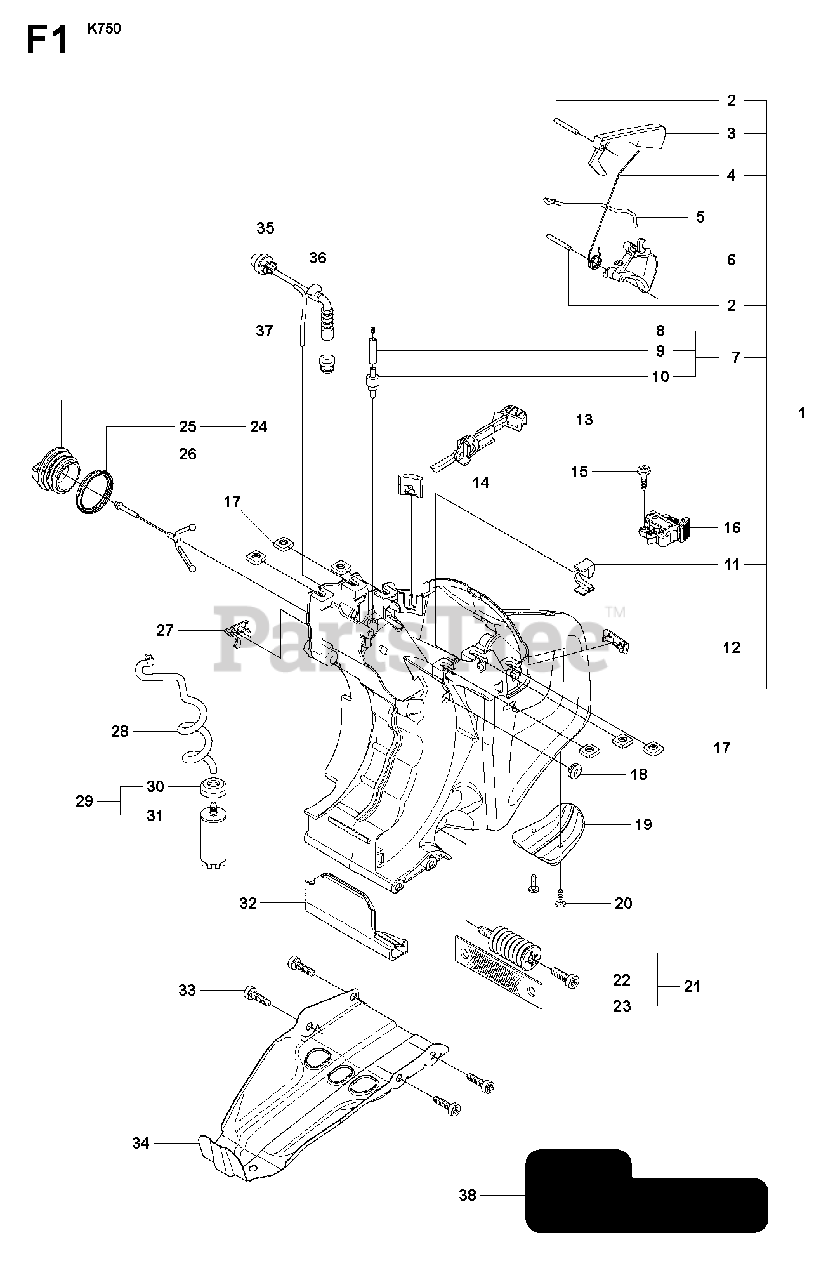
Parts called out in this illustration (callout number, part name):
1	FUEL TANKIncl. 2 - 4, 6 - 7, 11 - 12 Japan only
1	FUEL TANKIncl. 2 - 4, 6 - 7, 11 - 12
2	PARALLEL PIN
3	THROTTLE LOCKOUT
4	SPRING
5	THROTTLE ROD
6	THROTTLE TRIGGER
7	TANK VENT ASSYIncl. 8 - 10
13	CHOKE CONTROL
15	SCREW CCRPANT
16	STOP SWITCH
18	CABLE GROMMET
19	GROUND SUPPORT
20	SCREW CRCSFT
21	ANTIVIBRATION ELEMENTIncl. 22 - 23
22	SCREW ITXSCM
24	TANK CAP ASSYIncl. 25 - 26
28	FUEL HOSE
29	FUEL FILTERIncl. 30 - 31
33	SCREW ITXSCT
35	PURGEJapan only
36	FUEL HOSEJapan only
37	FUEL HOSEJapan only
38	LABELJapan only
